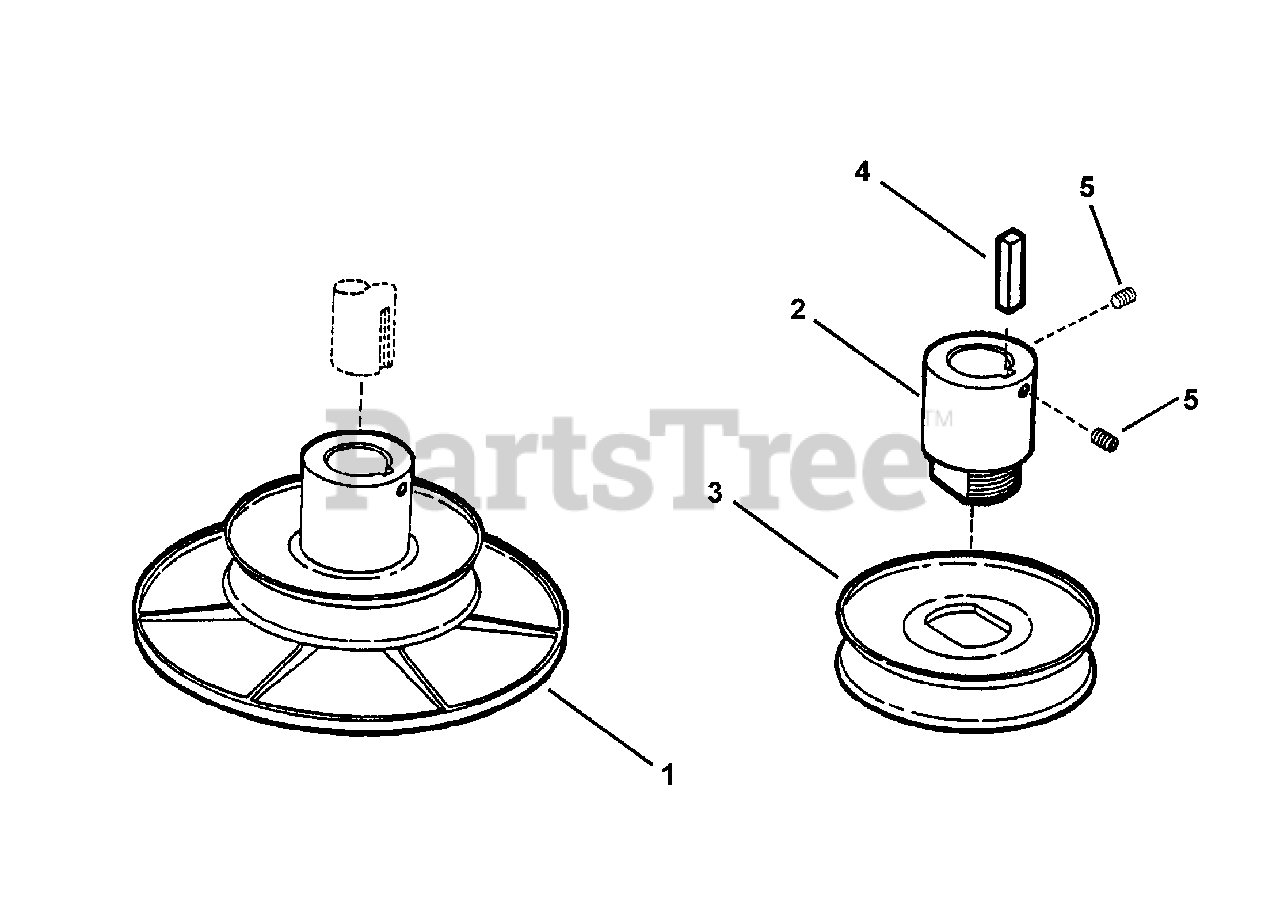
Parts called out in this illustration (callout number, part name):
1	ASSEMBLY, Drive Disc
2	HUB
3	PULLEY, Drive
4	KEY
5	SCREW, 3/8-16 x 3/8" Set
